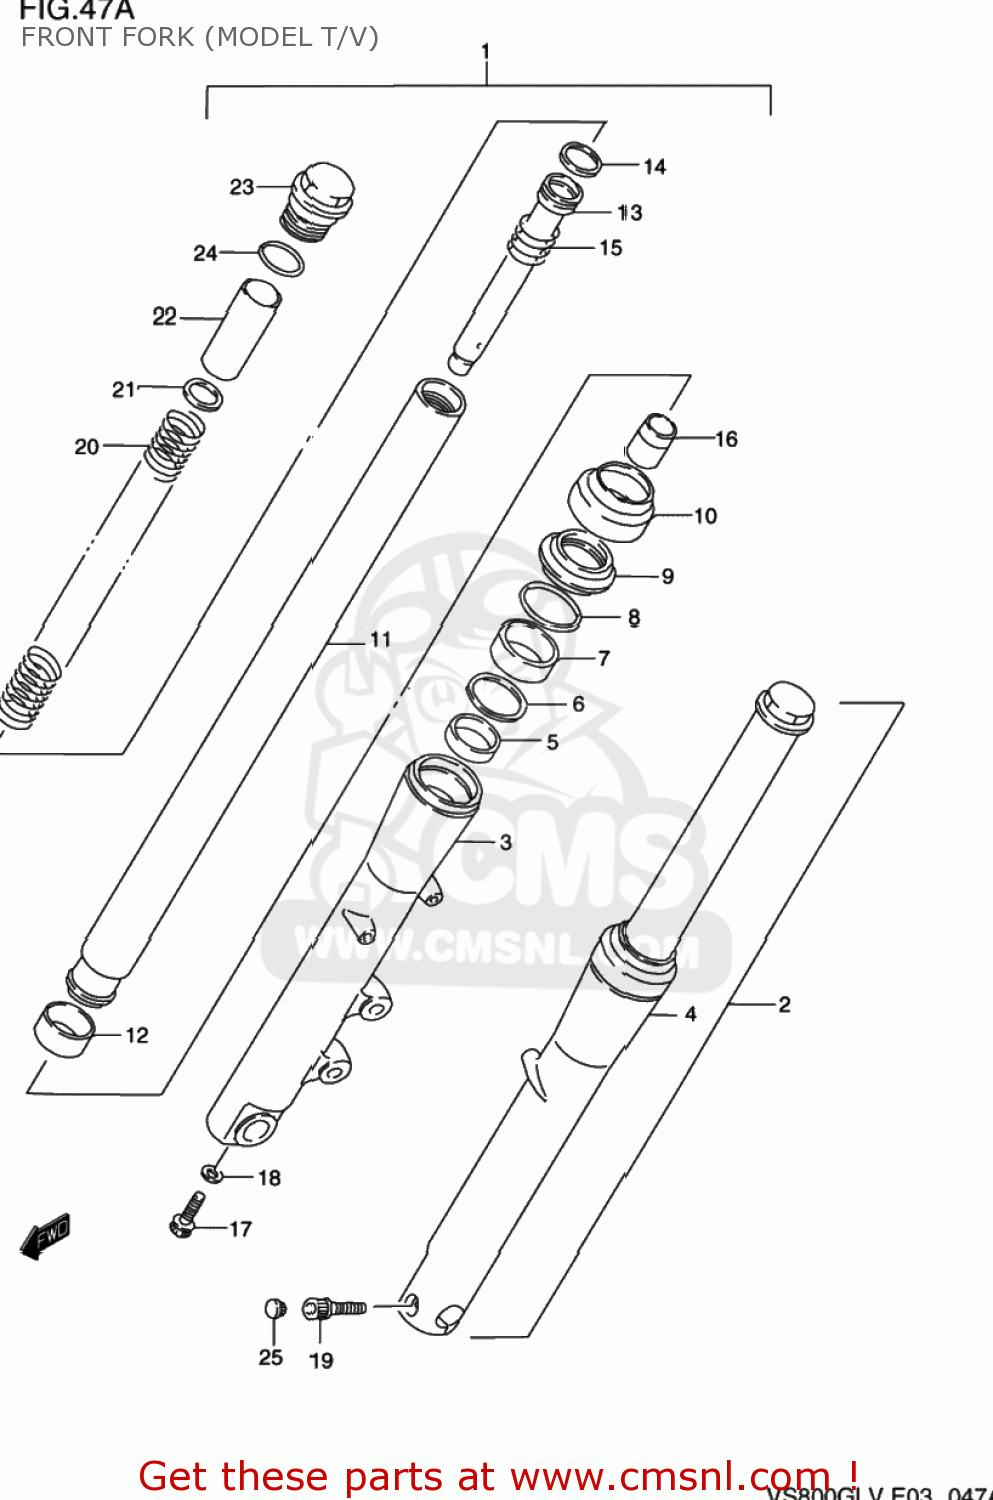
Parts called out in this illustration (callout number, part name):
1	DAMPER ASSY,FR FORK,R
2	DAMPER ASSY,FR FORK,L
3	TUBE,OUTER RH
4	TUBE,OUTER LH
5	BUSH,GUIDE
6	SPACER,SEAL
7	SEAL,OIL
8	RING,OIL SEAL STOPPER
9	SEAL,DUST
10	COVER,CASE
11	TUBE,INNER
12	BUSH,SLIDE
13	PIPE,SEAT
14	RING,PISTON
15	SPRING,REBOUND
16	PIECE,OIL LOCK
17	BOLT(8X27)
18	GASKET (NAS)
19	BOLT
20	SPRING
21	WASHER,SPRING
22	COLLAR,SPRING
23	BOLT,FORK
24	O RING
25	CAP(OD:14.5)
